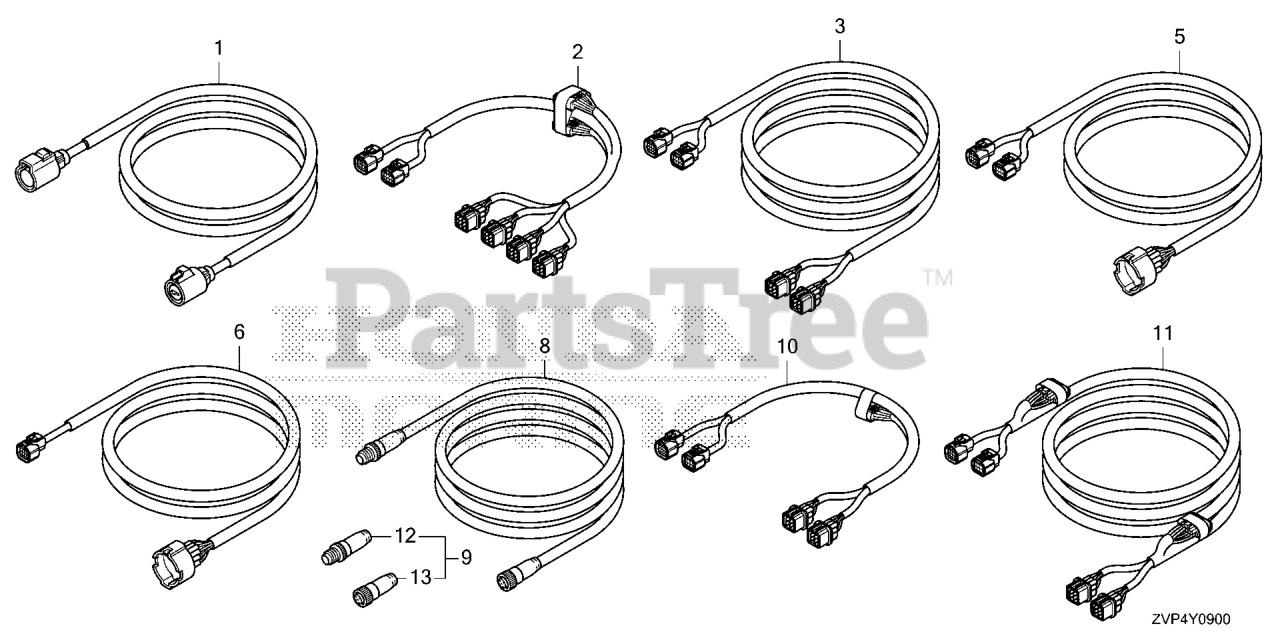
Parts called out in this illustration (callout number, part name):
1	WIRE ASSY., EXTENSION POWER
2	CABLE ASSY., BRANCH
3	CABLE ASSY., TRUNK (18FT) (DBW)
3	CABLE ASSY., TRUNK (24FT) (DBW)
3	CABLE ASSY., TRUNK (30FT) (DBW)
5	CABLE ASSY., ENGINE DROP (SINGLE 6FT)
5	CABLE ASSY., ENGINE DROP (SINGLE 16FT)
5	CABLE ASSY., ENGINE DROP (SINGLE 20FT)
5	CABLE ASSY., ENGINE DROP (SINGLE 25FT)
5	CABLE ASSY., ENGINE DROP (SINGLE 30FT)
6	CABLE ASSY., ENGINE DROP (6FT)
6	CABLE ASSY., ENGINE DROP (10FT)
6	CABLE ASSY., ENGINE DROP (14FT)
6	CABLE ASSY. (20FT)
8	CABLE ASSY., NETWORK (6FT)
8	CABLE ASSY., NETWORK (16FT)
8	CABLE ASSY., NETWORK (32FT)
8	CABLE ASSY., NETWORK (49FT)
9	CONNECTOR KIT, TERMINATOR
10	CABLE ASSY., BRANCH
11	CABLE ASSY. (38FT)
12	TERMINATOR (M)
13	TERMINATOR (F)
